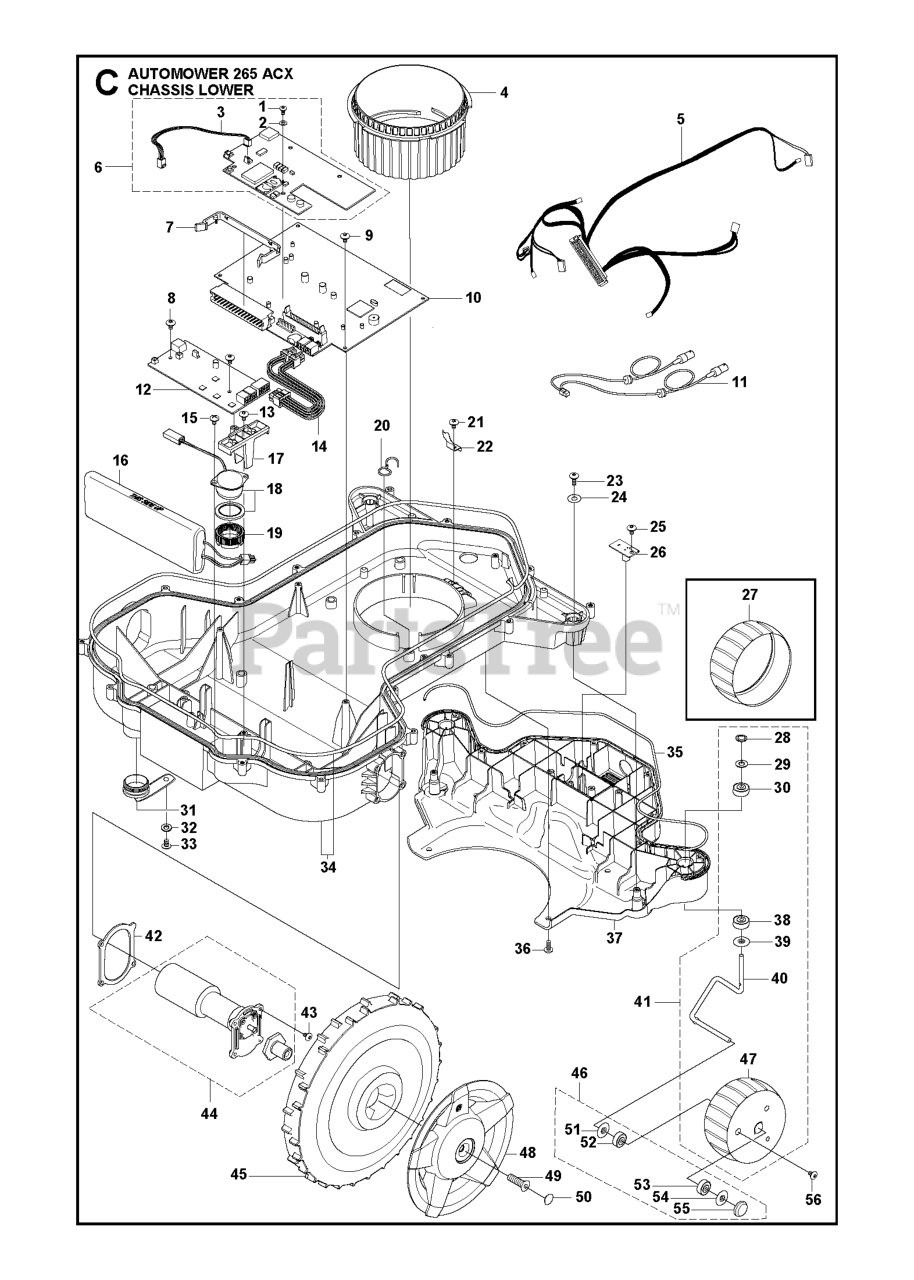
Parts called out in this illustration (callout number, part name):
1	SCREW GSM- MODULE
2	WASHER GSM- MODULE
3	LOOM LOOM GPS TRACKING MODULE
4	CUTTING HEIGHT NUT
7	CLIP MAIN CONNECTOR
7	CLIP MAIN CONNECTOR 50PCS
8	SCREW 12MM
9	SCREW SILVER 10MM
13	SCREW 14MM
15	SCREW
19	NUT BUZZER
23	SCREW 14MM
25	SCREW SILVER 10MM
26	PRINTED CIRCUIT ASSY
27	WHEEL RUBBER TYRE
28	LOCK WASHER PUSH-ON TYPE P 8 S
29	WASHER 16 OD X 6.5 ID X 1MM
30	BALL BEARING FRONT WHEEL AM 26
31	PLUG SERVICE PLUG
33	SCREW 14MM
36	SCREW 14MM
38	BALL BEARING FRONT WHEEL AM 26
39	WASHER FRONT WHEEL CENTER HOLE
42	GASKET
43	SCREW
44	DRIVE MOTOR
45	REAR WHEEL
46	KIT FRONT WHEEL BEARING KIT -
47	WHEEL, FRONT
48	HUB CAP
49	SCREW
50	COVER WASHER
51	WASHER FRONT WHEEL CENTER HOLE
52	BALL BEARING FRONT WHEEL AM 26
53	BALL BEARING FRONT WHEEL AM 26
54	WASHER FRONT WHEEL CENTER HOLE
55	COVER WASHER FRONT WHEEL AXEL
56	SCREW ITXPANT PT 40 THREAD
